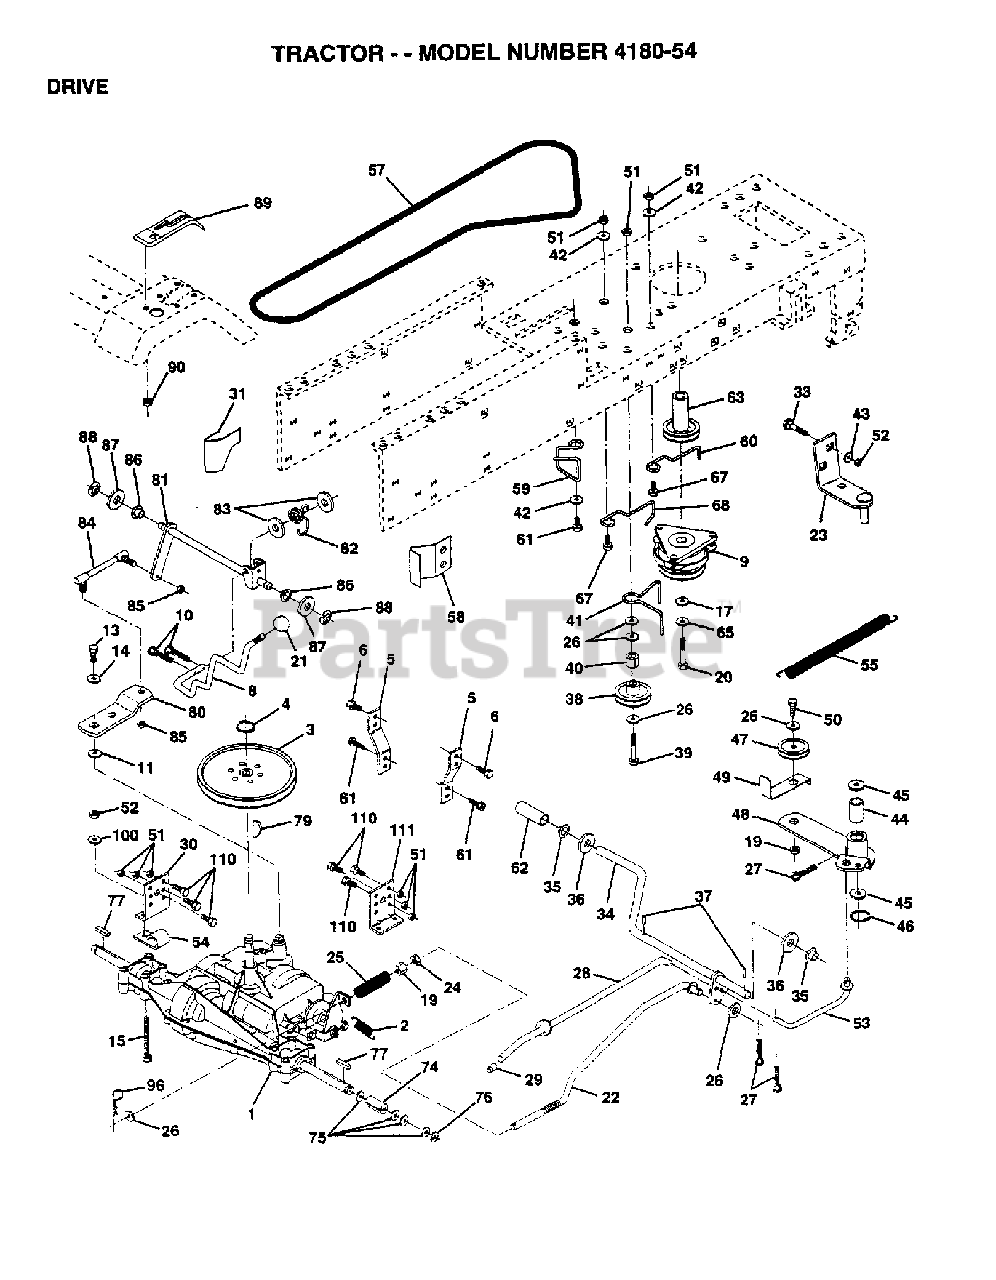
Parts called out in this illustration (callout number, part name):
2	SPRING T
3	PULLEY TRANSAXLE
5	STRAP TORQUE
6	Screw, Lt
8	ROD SHIFTER
10	PIN COTTER
11	WASH-SHFT PLT LT
14	WASHER PM
15	BOLT HEX
19	NUT
20	BOLT
21	KNOB T (1/2-HOLE)
22	ROD.ASM.BK.44.MWR (NLAD)
23	BRACKET ASM MTG
24	NUT
25	SPRING,ROD BRAKE
27	COTTER PIN
29	PLUNGER CAP
30	BRKT TRANS LH
31	KEEPER BELT LH
33	BOLT
35	BEARING.NYLON
36	WASHER LT
37	Drive Pin, 3/16 X 1"
38	FLAT IDLER PULLEY
40	SPACER T
41	BELT KEEPER LT
42	WASHER
43	WASHER T
44	BEARING LT (2 2)
45	WASHER LT
46	KLIP RING
47	Idler Pulley
49	RETAIN BELT
50	Hex Bolt
51	LOCKNUT
52	LOCKNUT
54	CLIP,INSULATOR
55	SPRING, RETURN LT
57	BELT.GROUND.DRIVE
58	KEEPER,BELT RH
62	PEDAL COVER
63	ENGINE PULLEY
65	LOCKWASHER
67	BOLT
68	KEEPER,BLT ENG LT
74	SPACER HYT
76	E RING HYT
79	KEY.WOODRUFF
80	ARM,SHIFT
81	SHAFT,SHIFTER
82	SPRING,TORSION
83	WASHER
85	NUT 1/4-28
86	BUSHING.STEERING.ROD
87	WASHER D
88	KLIP RING
90	NUT.PUSH.3/16
96	RETAINER M
100	WASHER M
111	BRKT TRANS RH
